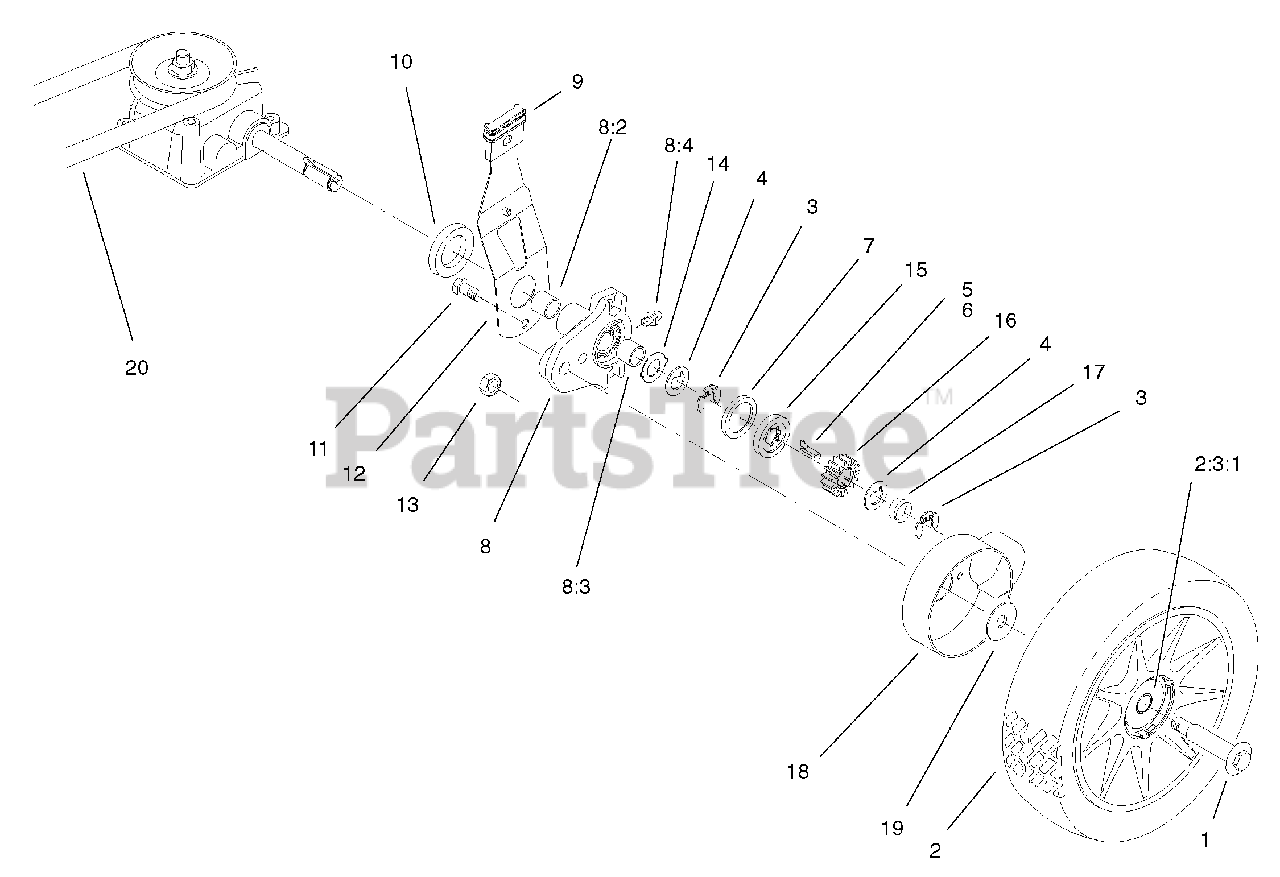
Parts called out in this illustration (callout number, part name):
1	Bolt-Shoulder
2	Wheel & Tire ASM
2:3	Wheel & Tire ASM
3	Ring-Klip
4	Washer-Thrust, Keyed
5	Key-Rocking, LH
7	Ring-Friction
8	Rear Height Adjustment Arm ASM
8:4	Fitting-Zerk
9	Knob-Lever, Height Adjustment
10	Spacer-Axle Shaft
12	Rear Spring Arm ASM
14	Washer-Arm, Pivot
15	Washer-Clutch
16	Gear-Pinion
17	Spring-Compression
18	Cover-Wheel
19	Washer-Stepped
